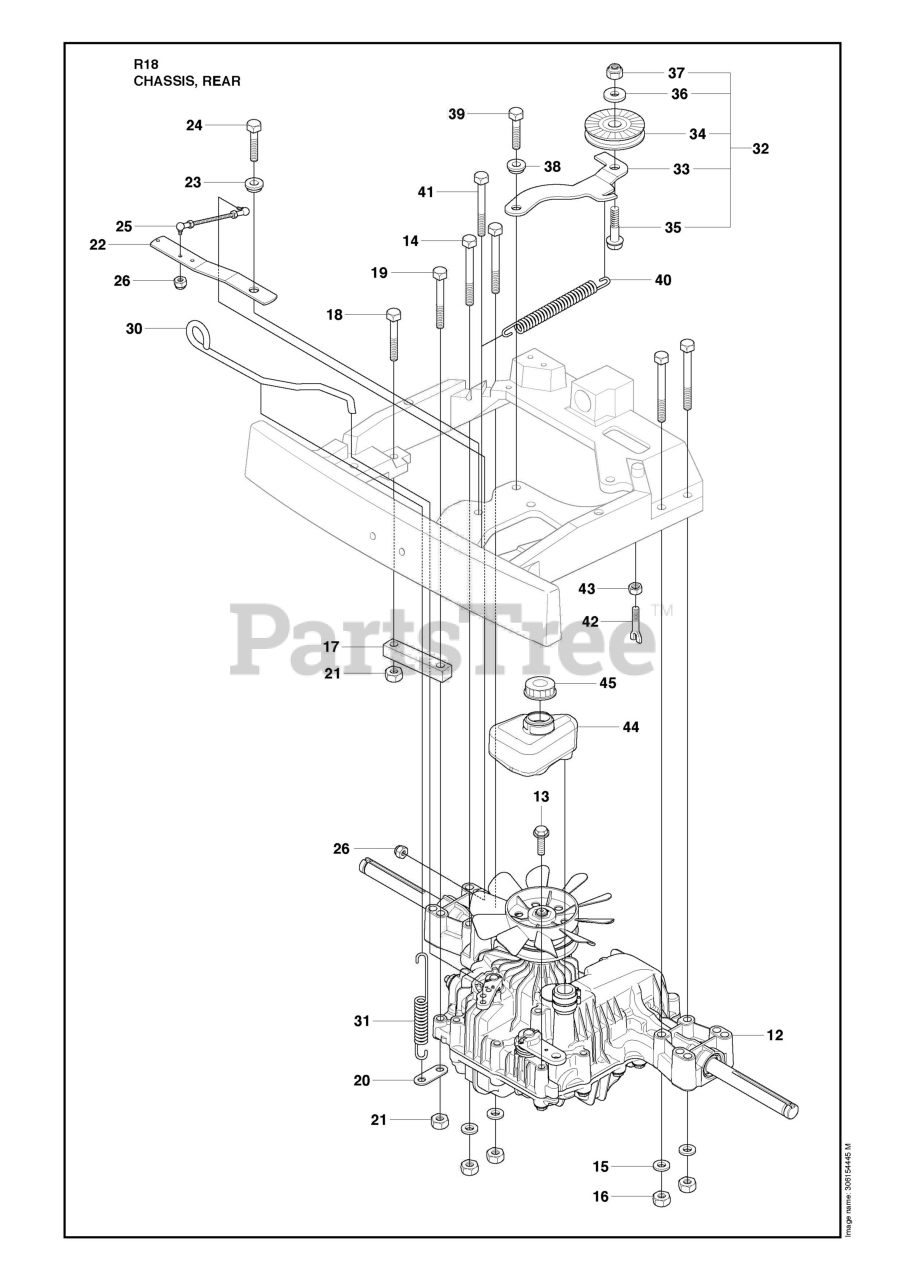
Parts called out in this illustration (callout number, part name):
2	Ball Bearing
3	BALL BEARING 6010 2RS1
4	CIRCLIP SGH 47
5	RETAINING RING SGA 25
7	RETAINING RING SGA 25
12	HYDROSTAT 7A646024070
15	WASHER BRB 8.4X17
16	NUT
21	NUT
23	WASHER
24	SCREW 8X20
26	LOCKNUT M5
33	TENSIONER
35	SCREW
37	LOCKNUT M8
38	WASHER
39	SCREW 8X20
43	NUT
45	TANK CAP
47	REPL BY 725 25 00-71
48	COUNTERWEIGHT
